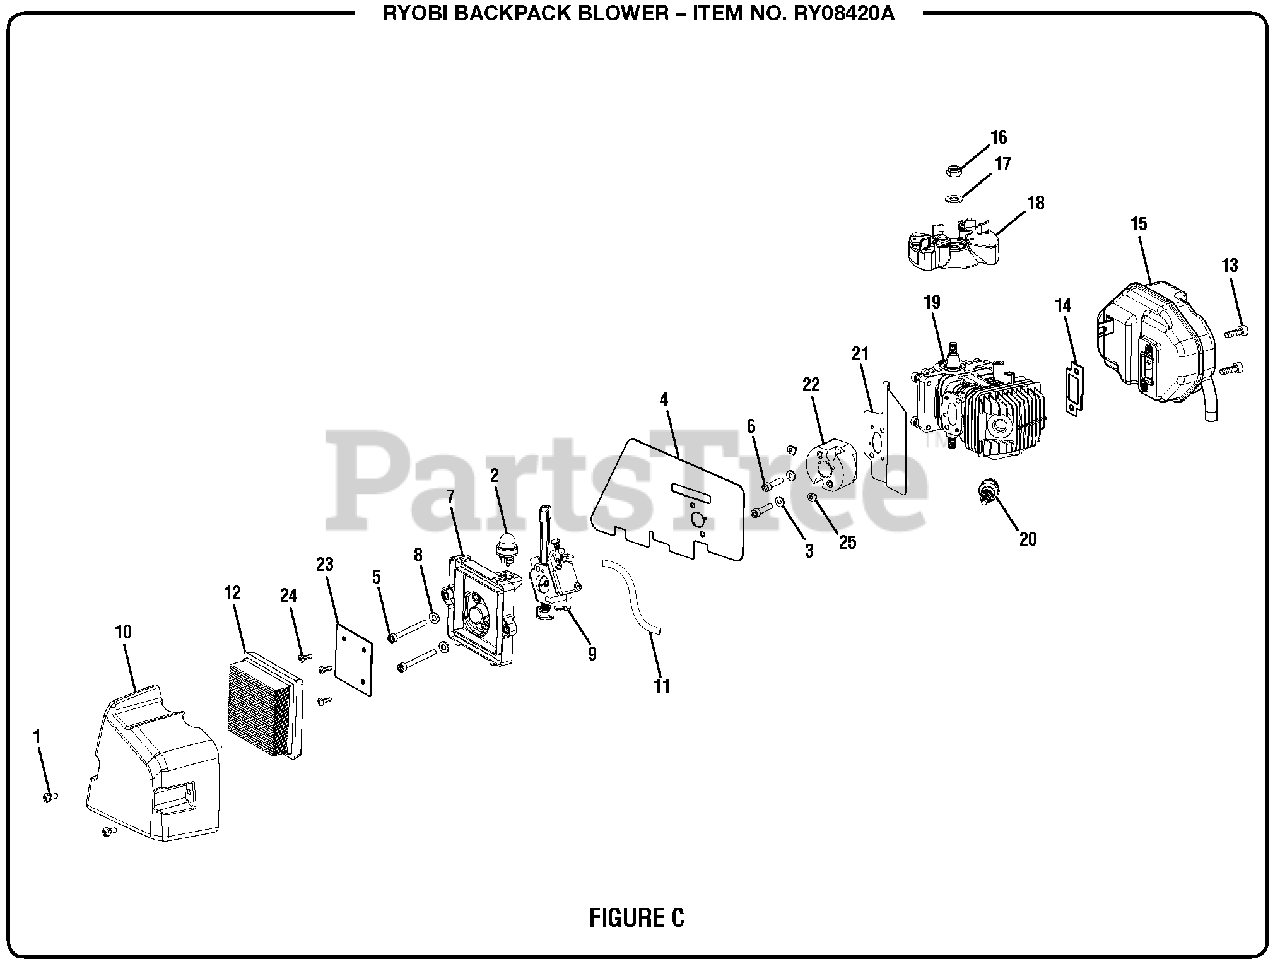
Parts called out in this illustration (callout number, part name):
1	Screw (M5, Special)
2	Primer Assembly
3	Spring Washer (M5)
5	Screw (M5 x 50 mm, Soc. Hd.)
6	Screw (M5 x 0.8 in.)
7	Air Box Base
8	Washer (ID5.8 x OD11.5 x 1.7t)
9	Carburetor (Walbro, WT-1086)
10	Air Box Cover
11	Fuel Line
12	Air Filter
13	Bolt (1/4-20 x 18 mm)
15	Exhaust Assembly
16	Lock Nut (M8)
17	Washer (ID9 x OD17.7 x 1.1t)
18	Flywheel Assembly
19	Short Block Assembly
20	Spark Plug (RCJ4)
24	Screw (M4 x 12 mm, Pan Hd.)
25	Washer (Heat Dam)
